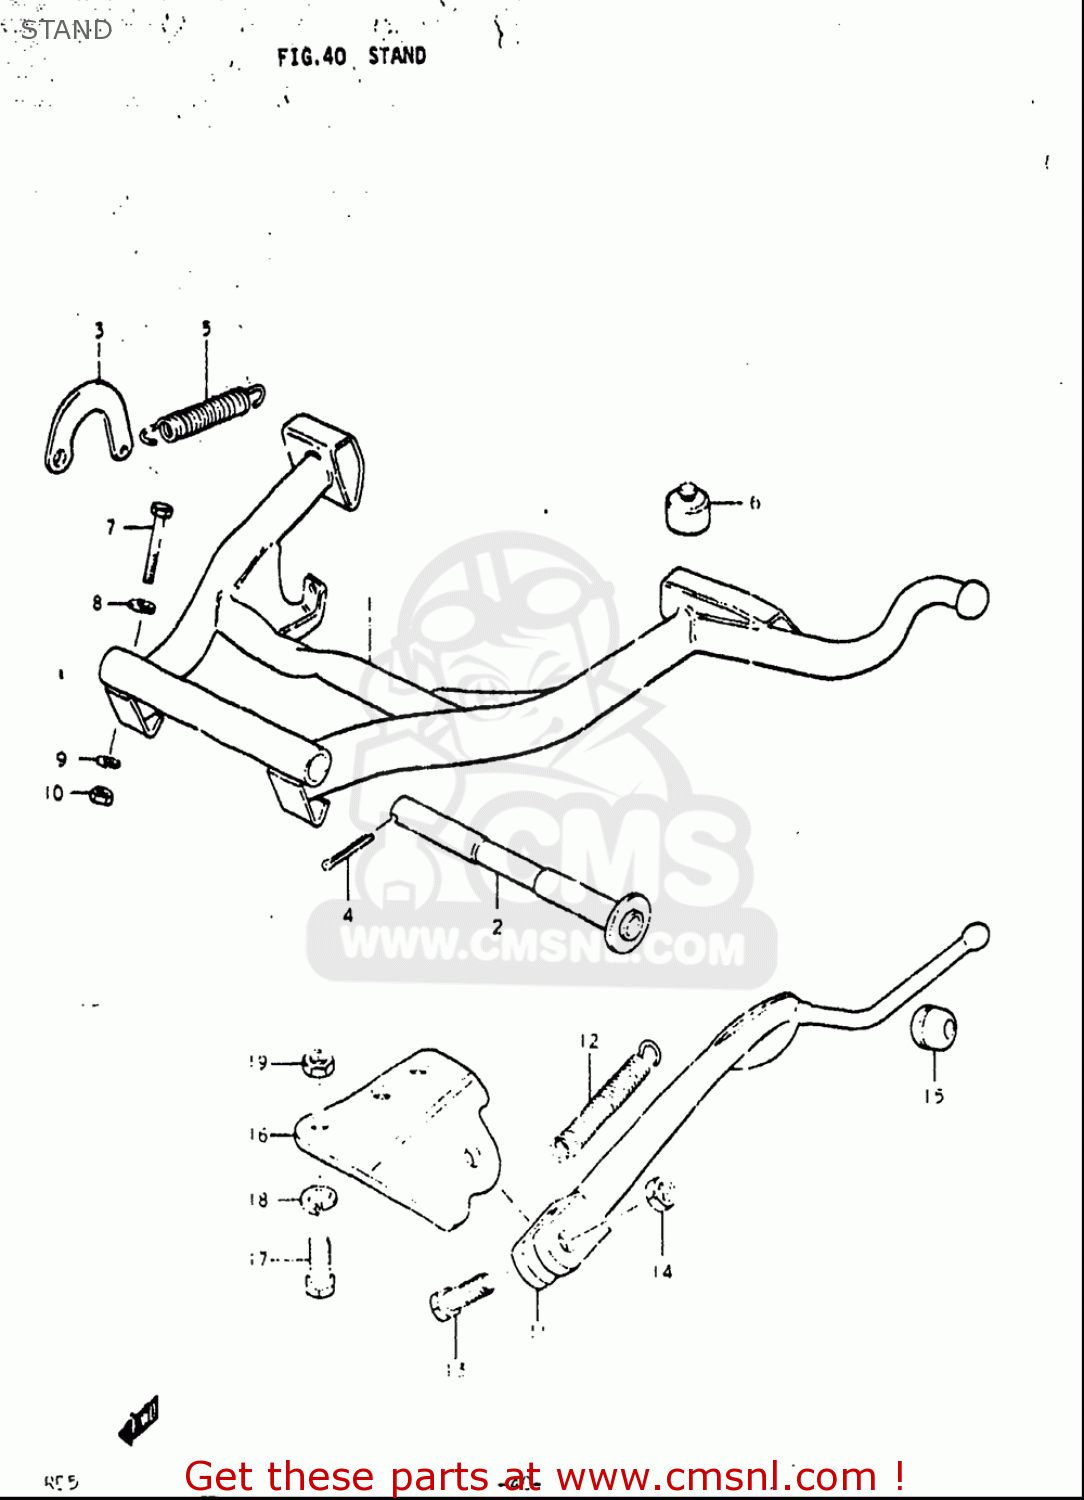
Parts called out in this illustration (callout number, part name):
4	PIN
5	SPRING
6	CUSHION
7	BOLT
8	WASHER
9	WASHER,LOCK
10	NUT
12	SPRING
13	BOLT(10X30)
14	NUT
15	CUSHION
17	BOLT(10X27)
18	WASHER,LOCK
19	NUT
